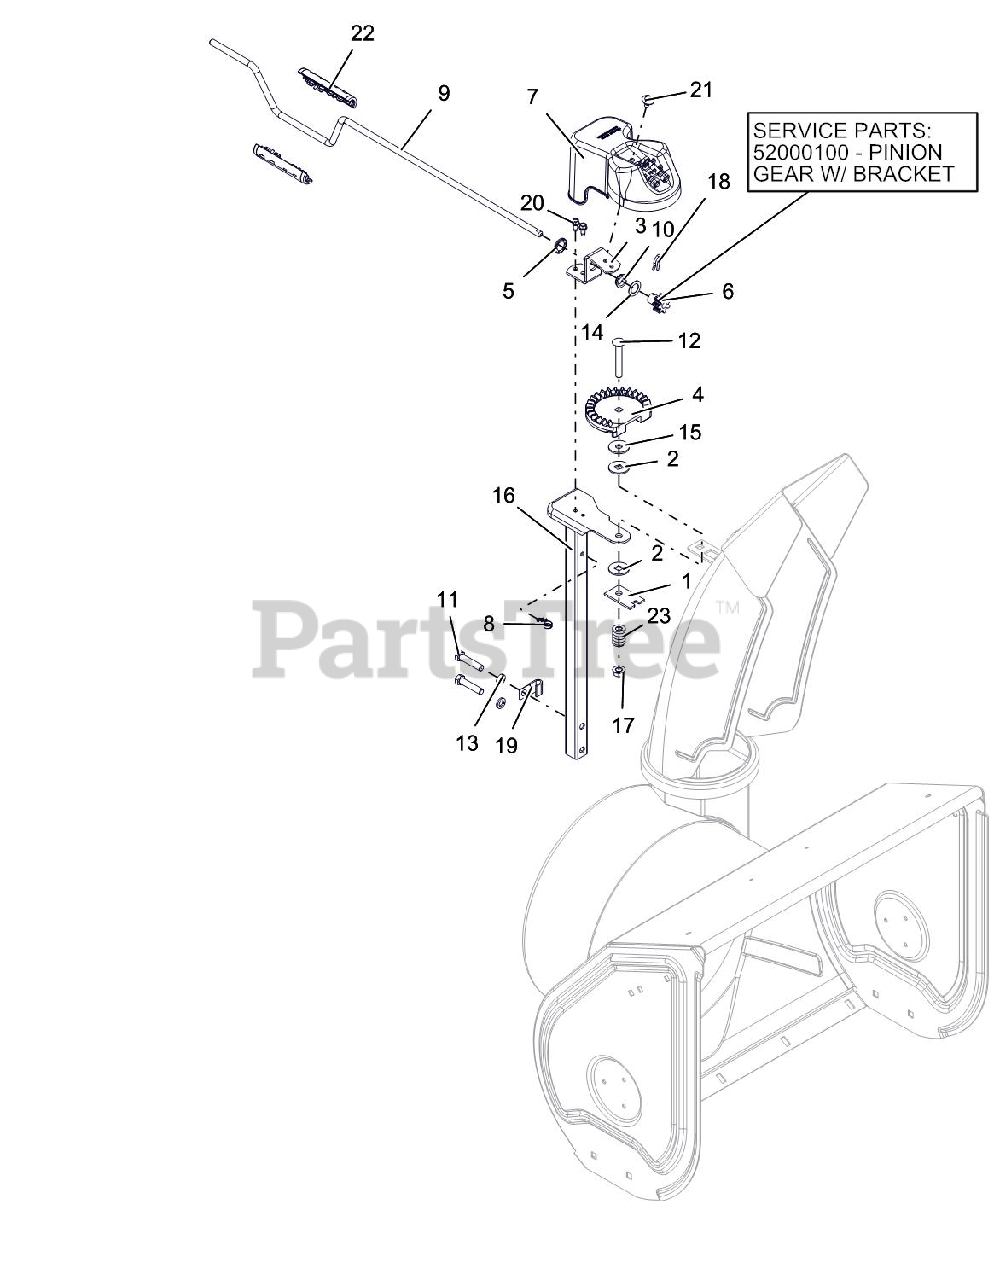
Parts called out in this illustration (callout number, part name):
1	PLATE, FRICTION
2	FRICTION WASHER
3	BRACKET, PINION GEAR
4	CHUTE GEAR
5	PUSHNUT .625
6	PINION GEAR W/BRACKET
6	PINION GEAR - CHUTE
7	GEAR COVER ASSY LG SHEAR BOLT
8	CLIP, CABLE GUIDE
9	ROD,CRANK - SMDASH DLX
10	BUSHING, POLYLINER-.63 SNAPIN
11	@BLT-HEX .38-16X1.75 GR5 YWZC
12	@BLT-RDHDSQNK .38-16X2.50 G5YZ
13	@WSHR-LK .38X.094 REG YWZC
14	WSHR-THRST .625 X 1.0 X .03
15	@WSHR-FL-STL .406X1.25X.10 ZC
16	PEDESTAL, CHUTE - CRANK
17	@NUT-LK-TOP-FLG .38-16 YWZC
18	PIN, SPRING CLIP
19	J-CLAMP
20	SCR-TAP .25-20X.50 HWH TR YWZ
21	SCR-TAP .25-20X.50 LGHWH TR YZ
22	KNOB,CHUTE CRANK-DELUXE
23	SG-COMP .187X.56X1.62
